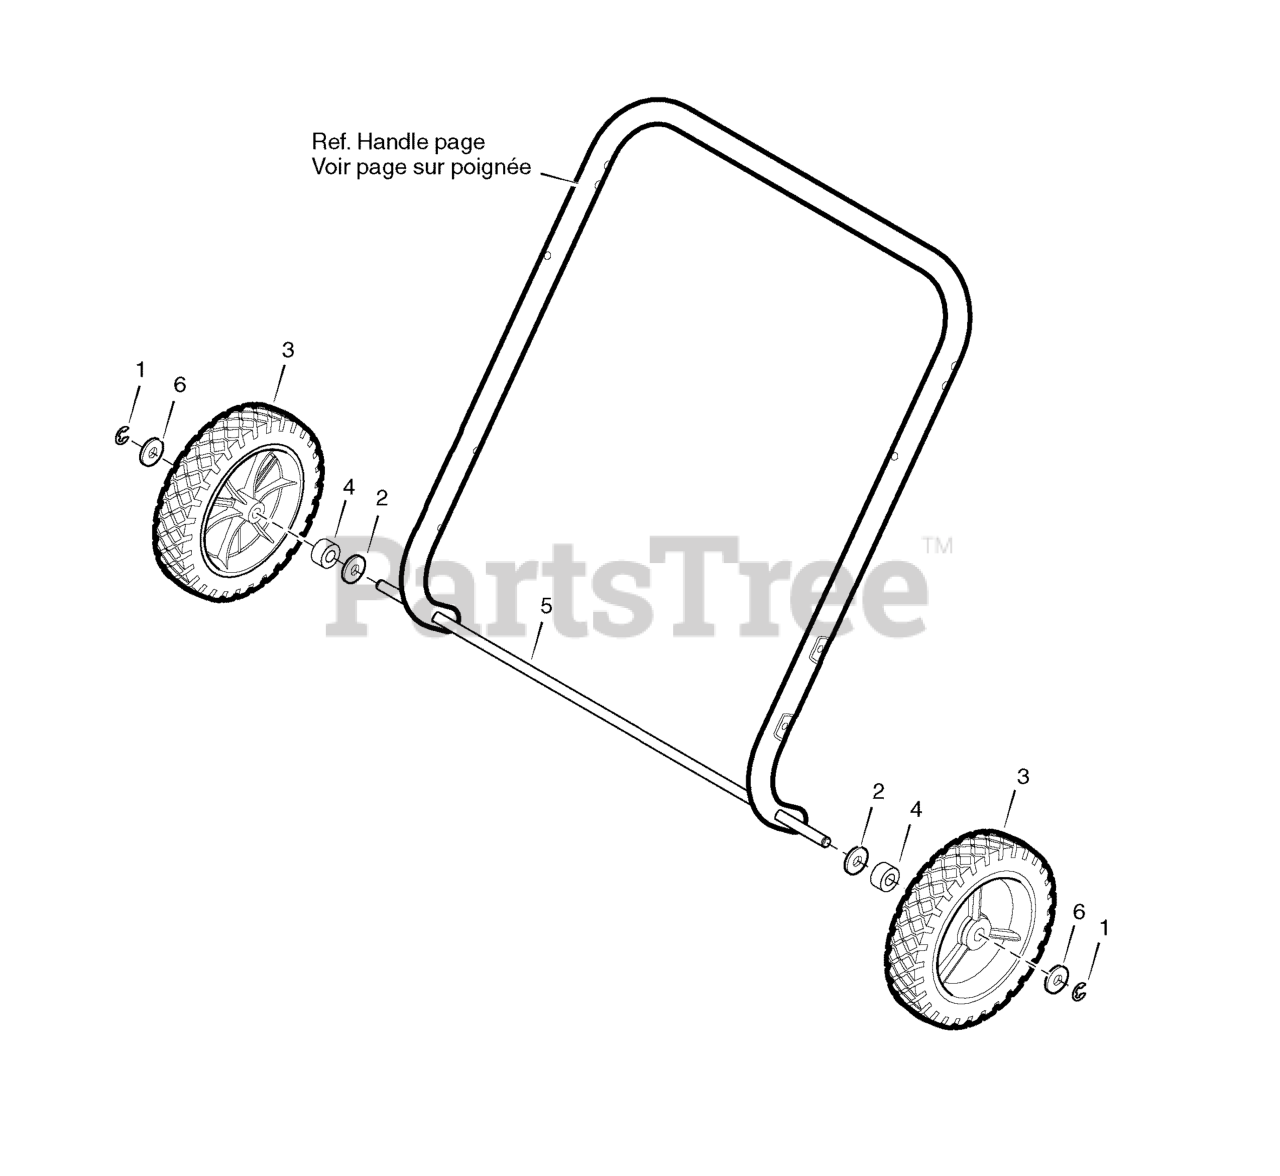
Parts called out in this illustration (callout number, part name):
1	Retainer, E-Ring
2	WASHER, Flat, 13/32
3	Wheel and Tire 7" x 1.50"
4	Sleeve, Spacer
5	Rod, Axle
